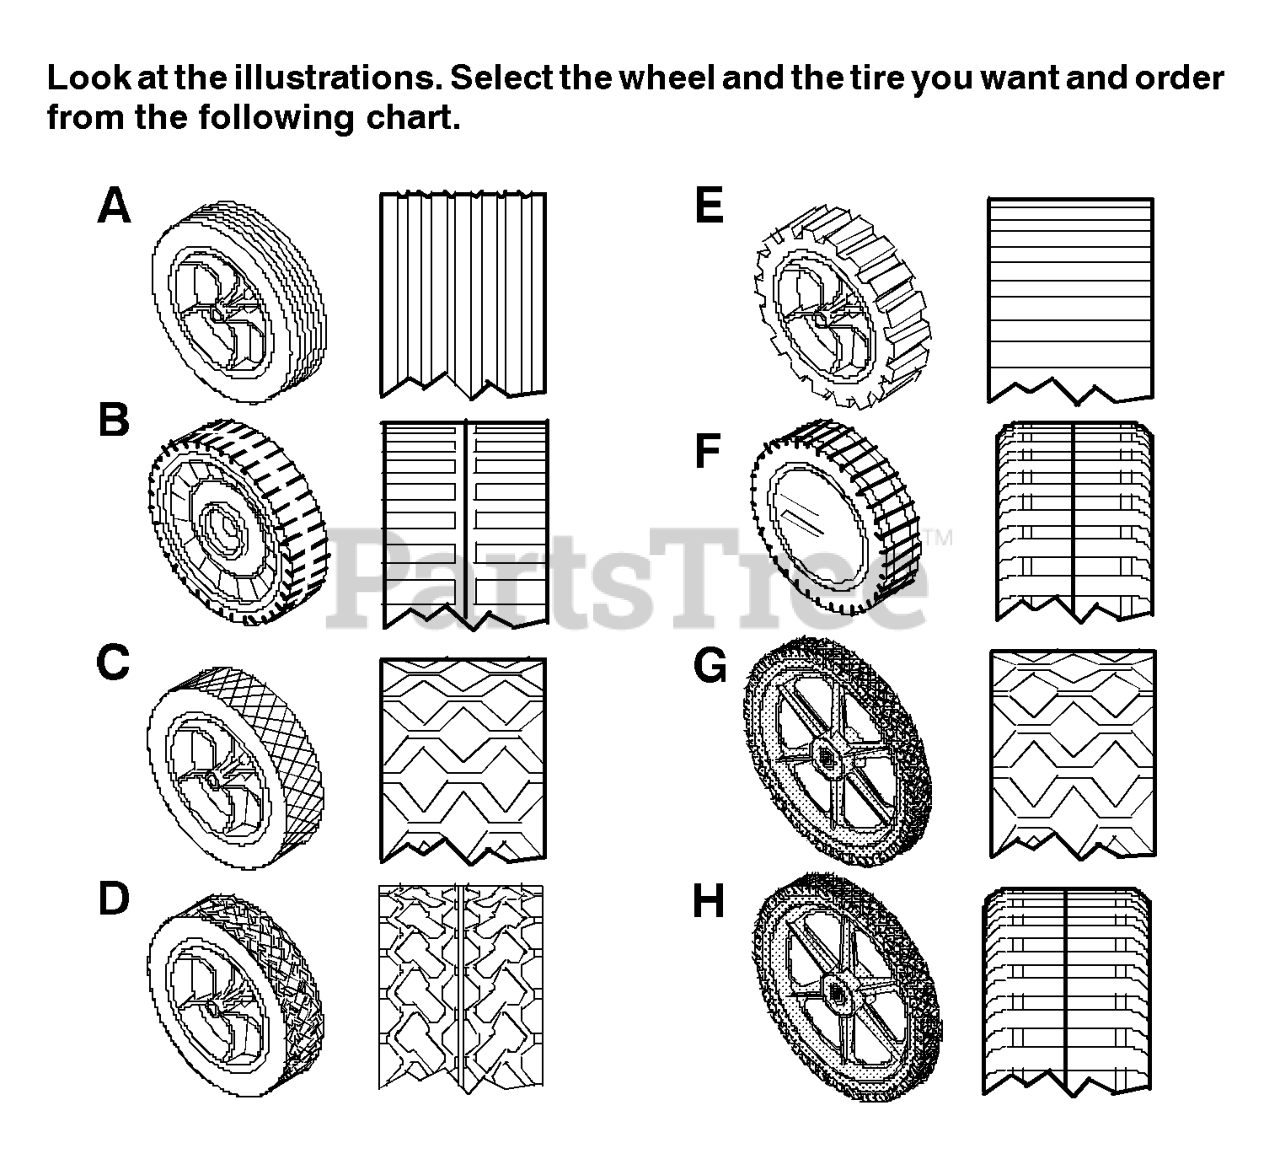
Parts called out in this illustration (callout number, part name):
A	WHEEL & TIRE ASSEMBLY, Light Gray, 8"
A	8-inch Plastic, Dark Gray
A	8-inch Metal, White
B	7-inch Plastic, White
B	7-inch Plastic, Light Gray
B	7-inch Plastic, Dark Gray
C	6-inch Plastic, White
C	7-inch Plastic, White
C	7-inch Plastic, Light Gray
C	7-inch Plastic, Dark Gray
C	8-inch Plastic, White
C	8-inch Plastic, Light Gray
C	8-inch Plastic, Dark Gray
C	8-inch Metal, White
D	7-inch Plastic, White
D	WHEEL & TIRE ASSEMBLY, White, 8"
D	8-inch Plastic, Light Gray
D	8-inch Plastic, Dark Gray
E	WHEEL & TIRE ASSEMBLY, White, 8"
E	8-inch Plastic, Dark Gray
E	8-inch Metal, White
F	WHEEL & TIRE ASSEMBLY, White, 8"
F	8-inch Plastic, Light Gray
F	8-inch Plastic, Dark Gray
F	8-inch Ball Bearing, Light Gray
F	8-inch Ball Bearing, Dark Gray
G	14-inch, White
G	14-inch, Light Gray
G	14-inch, Dark Gray
G	WHEEL & TIRE ASSEMBLY, White, 14"
G	14-in, Ball Bearing, Light Gray
G	14-in, Ball Bearing, Dark Gray
H	14-inch, White
H	14-inch, Light Gray
H	14-inch, Dark Gray
H	WHEEL & TIRE ASSEMBLY, Ball Bearing, 14"
H	14-in, Ball Bearing, Light Gray
H	14-in, Ball Bearing, Dark Gray
